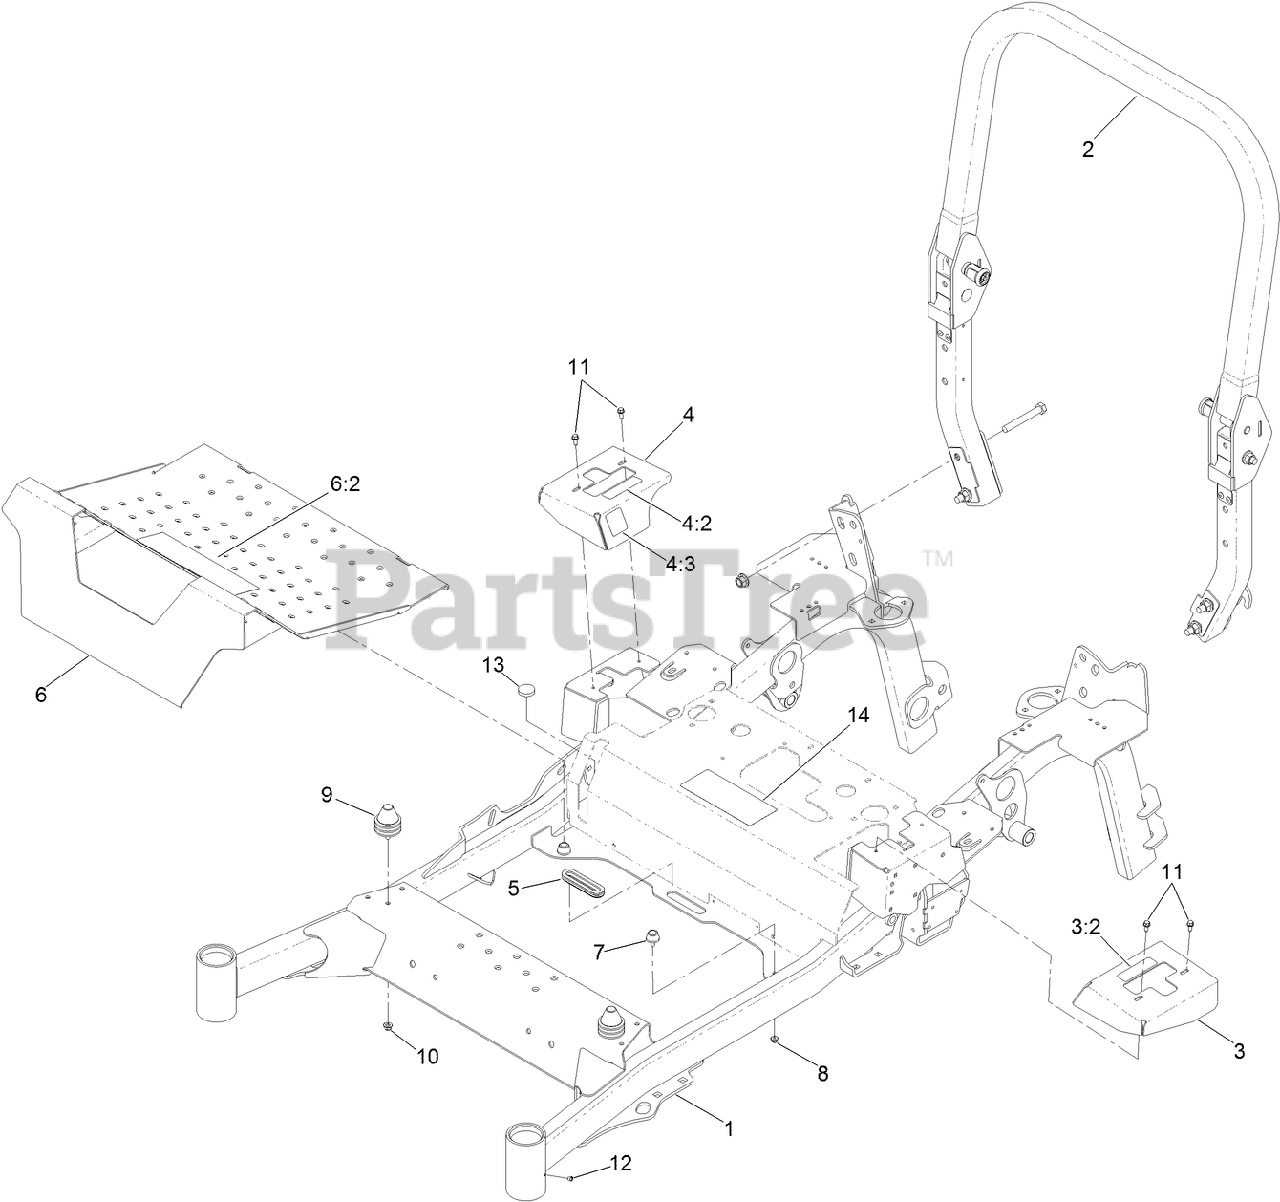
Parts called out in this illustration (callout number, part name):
3	COVER-MOTION CONTROL, LH
3:2	DECAL-CONTROL, MOTION
4	COVER-MOTION CONTROL, RH
4:2	DECAL-CONTROL, MOTION
4:3	DECAL-PARK BRAKE, CE
5	GROMMET-RUBBER
6	PAN-FLOOR
6:2	DECAL-DANGER
7	BUMPER-RUBBER
8	NUT-HF
9	ISOLATOR
10	NUT-HF, NI
11	SCREW-HWH
13	BUMPER-PUSH-IN, RUBBER
14	DECAL-SERVICE AID
